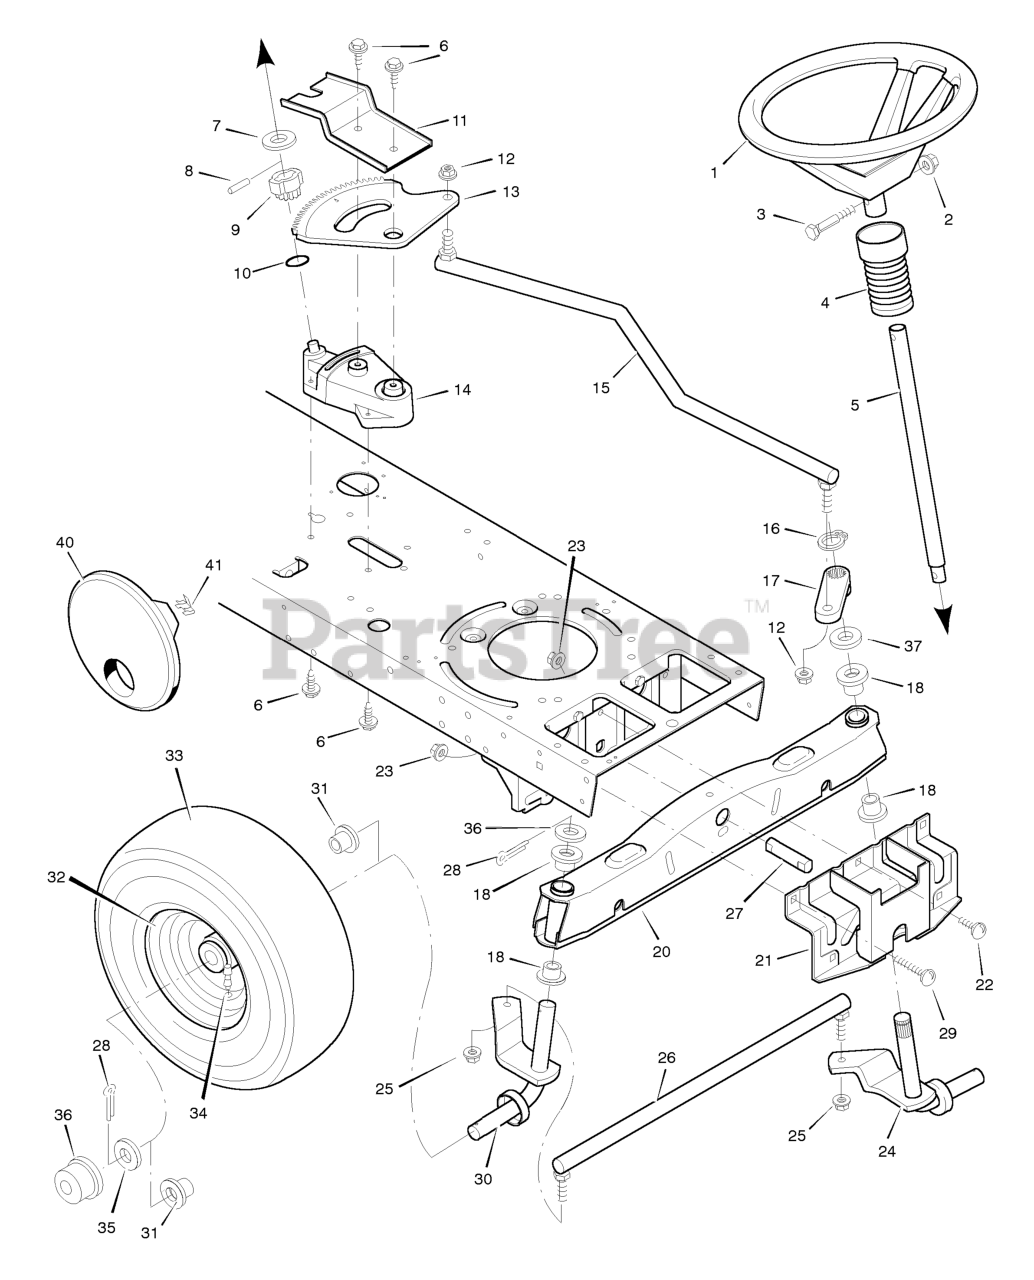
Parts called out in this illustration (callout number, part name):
1	Wheel, Steering
2	Nut, Hex
3	Bolt, Hex
4	Bellows
5	Post Assembly, Steering
7	Washer
8	Pin, Spring
9	Gear Assembly, Pinion
10	O- Ring
11	Clip, Gear Retainer
12	Locknut, Flange
13	Gear, Sector
14	Support, Steering
15	Link, Drag
16	E- Ring
17	Arm, Drag Link
18	Bearing
20	Axle Assembly (with grease fittings)
21	Hanger Assembly, Axle
22	Bolt, Carriage
23	Locknut, Flange
24	Spindle Assembly, Left
25	Locknut, Flange
26	Rod, Tie
27	Pin, Pivot
28	Pin, Cotter
29	Bolt, Carriage
30	Spindle Assembly, Right
31	Bearing, Wheel
32	Wheel & Tire Assembly
33	Tire *
34	Stem, Valve
36	Hub Cap
40	Disc, Wheel (8 inch)
41	Clip, Retainer
